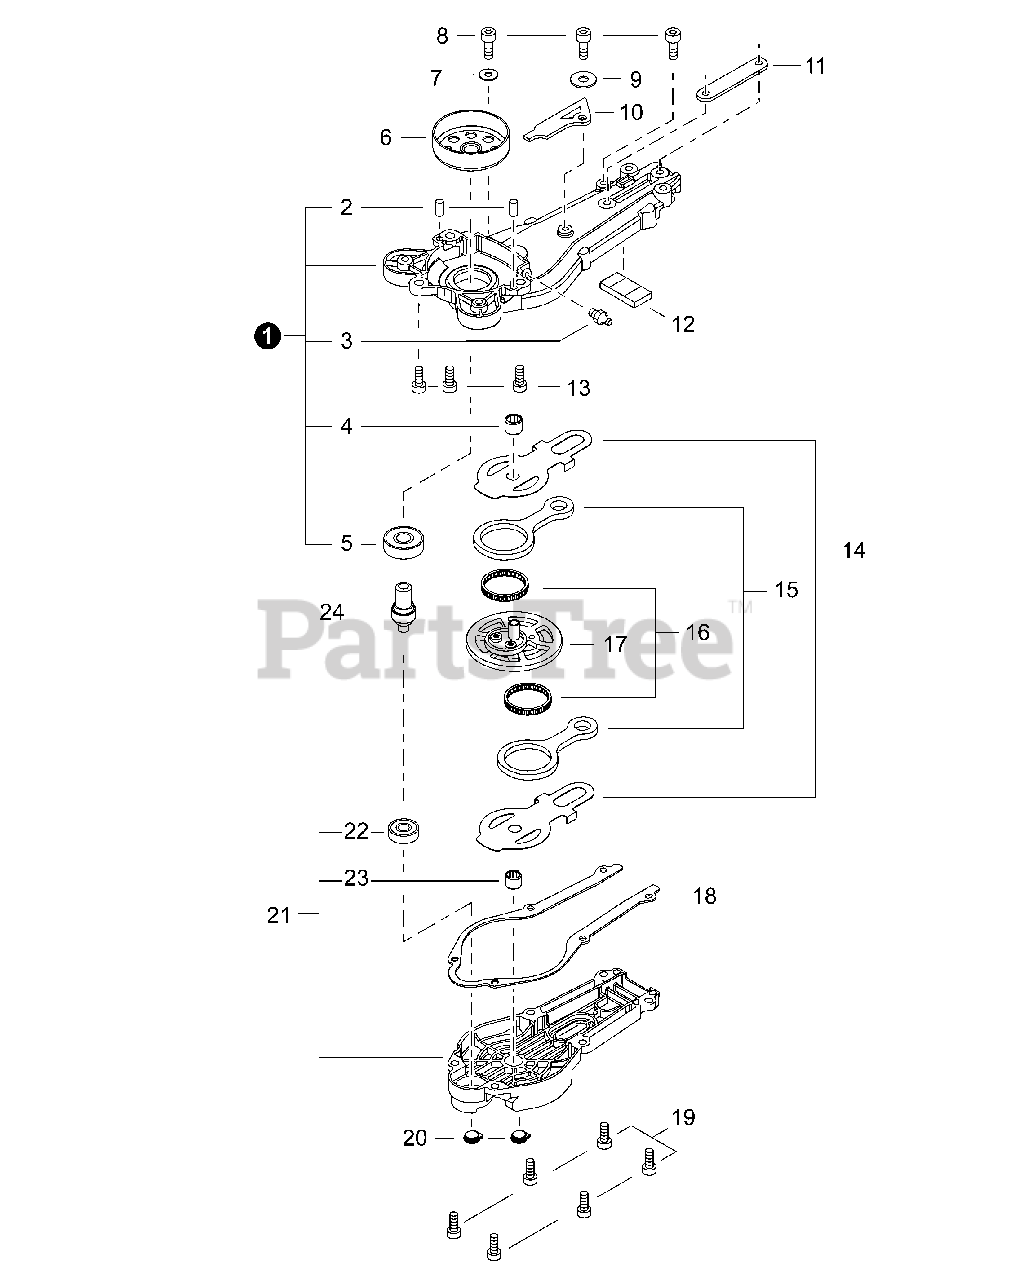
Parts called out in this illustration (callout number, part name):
1	GEAR CASE HOUSING ASSY
2	PIN, LOCATING 4×8
3	FITTING, GREASE
4	BEARING, NEEDLE 8
5	BEARING, BALL 6001 DDU
6	DRUM, CLUTCH
7	WASHER 5.3×10×1
8	BOLT, TORX 5
9	WASHER 5
10	CUSHION
11	PLATE, EYE
12	PACKING, FELT
13	BOLT, TORX 6×20
14	PLATE, SIDE
16	BEARING, NEEDLE 30
17	GEAR, SPUR
18	GASKET, GEAR CASE
19	BOLT, TORX 5×16
21	COVER ASSY, GEAR CASE
22	BEARING, BALL 608ZZ
23	BEARING, NEEDLE 8
24	SHAFT, PINION
